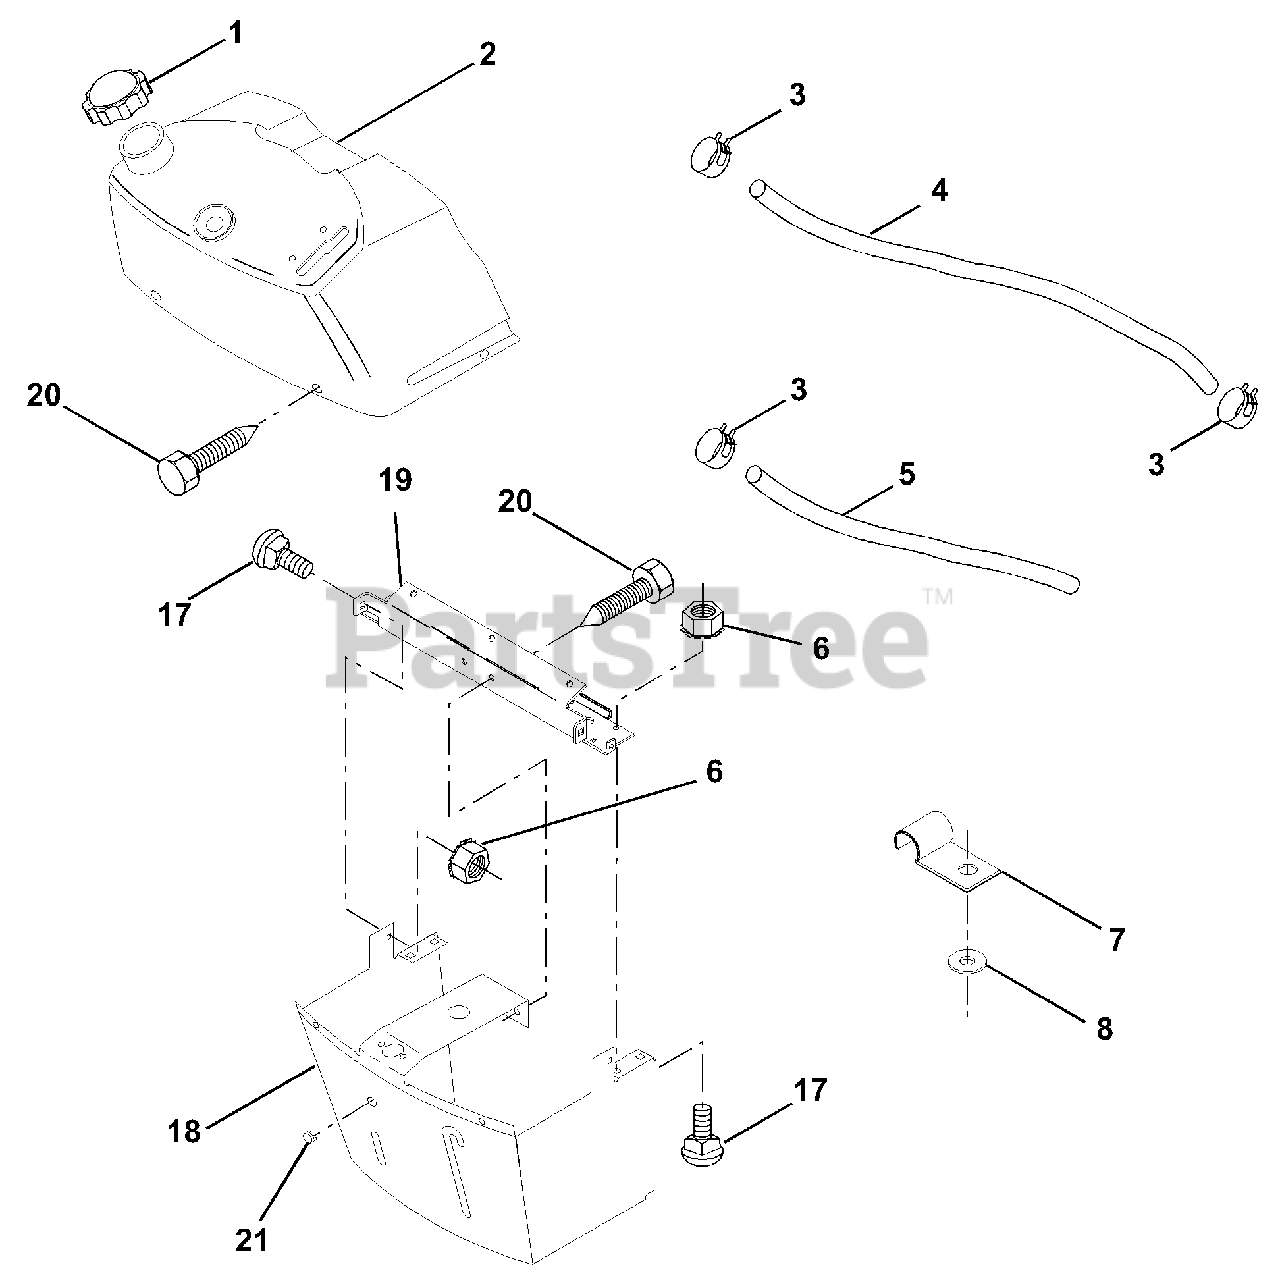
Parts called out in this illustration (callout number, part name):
1	Cap, Fuel Tank
2	Assembly, Dash & Fuel Tank
3	Clamp, Hose
4	Line, Fuel
5	Line, Fuel
6	Nut, Hex, Keps 1/4-20
7	Clip, Fuel Line
8	Washer 9/32 x 3/4 x 16 Gauge
17	Bolt, Carriage 1/4-20 x 1/2 Grade 5
18	Support Assembly, Dash
19	Brace, Cross
20	Screw, Self-Tapping 1/4-20 x 1/2
21	Plug, Dome, Black
